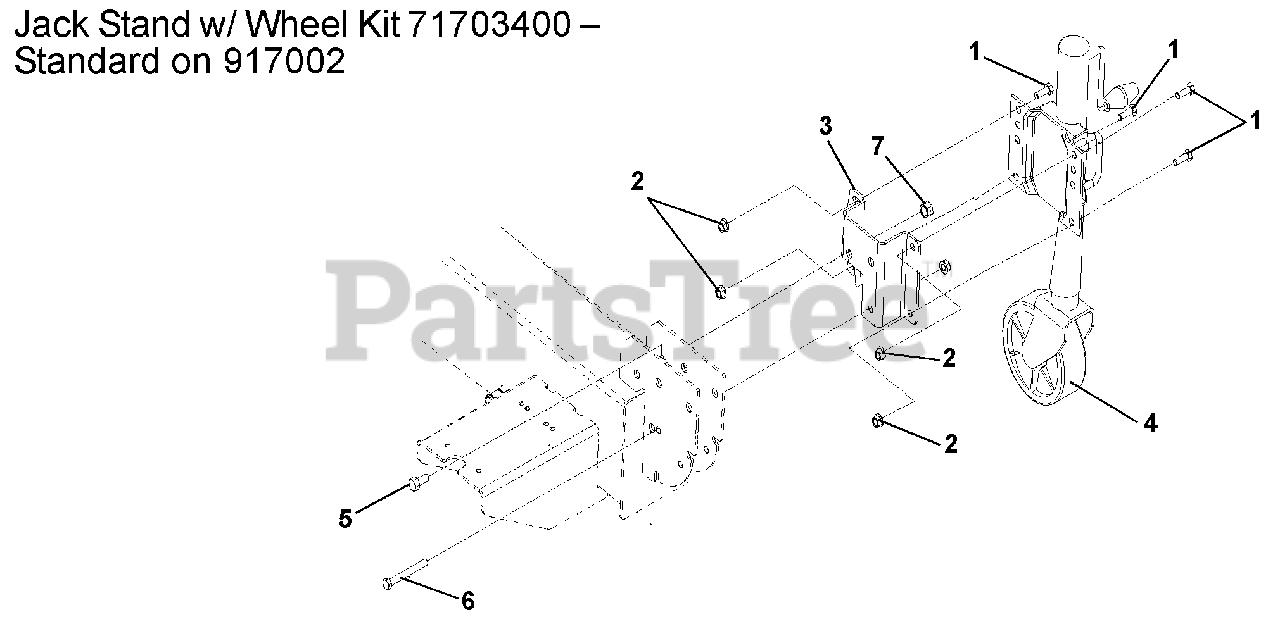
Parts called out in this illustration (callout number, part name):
1	@BLT-HEX .38-16X1.00 GR5 YWZC
2	@NUT-LK-TOP-FLG .38-16 YWZC
3	BRACKET, MOUNTING
4	STAND, JACK-W/WHEEL
5	@BLT-HEX .50-13X1.00 GR5 YWZC
6	@BLT-HEX .38-16X3.25 GR5 YWZC
7	NUT-LK-CTR-FLG .50-13 YWZC
